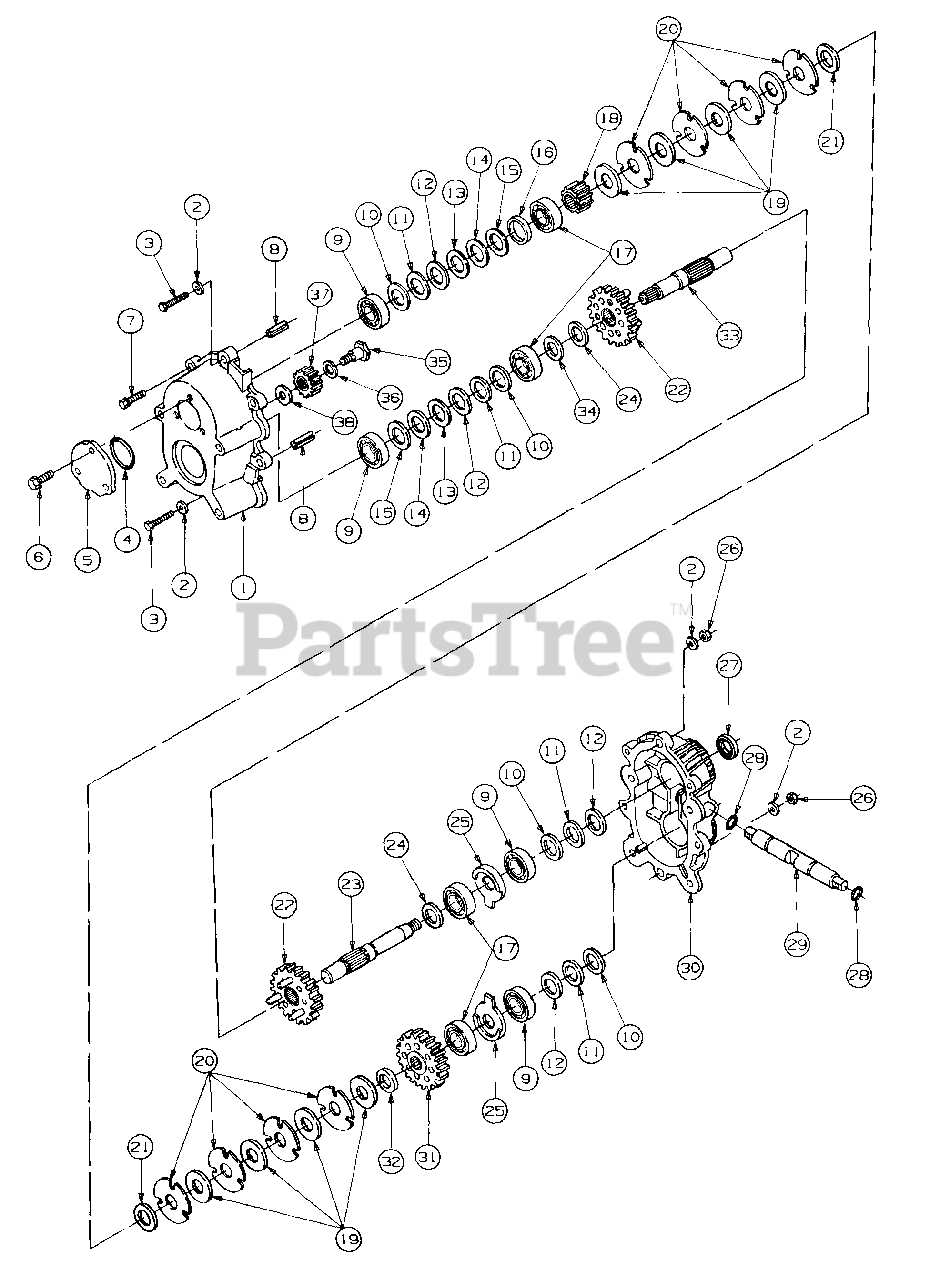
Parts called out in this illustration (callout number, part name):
1	Housing, Rear Clutch
2	Washer, Flat, .25 x .62 x .052 Thk
3	Screw, Hex Cap, 1/4-20 x 1.5 Lg
4	O-Ring, 1.88 x .103
5	Plate, Clutch Shim
6	Screw, Hex TT-Tap, 1/4-20 x .62 Lg
7	Screw, Hex Wash TT-Tap, 1/4-20 x 1.0 Lg
8	Pin, Slotted Spring, 7/16 x 1.0 Lg
9	Bearing
10	Washer, Flat, 1.25 x 1.8 x .005 Thk
11	Washer, Flat, 1.25 x 1.8 x .010 Thk
12	Washer, Flat, 1.25 x 1.8 x .015 Thk
13	Washer, Flat, 1.25 x 1.8 x .020 Thk
14	Washer, Flat, 1.25 x 1.8 x .025 Thk
15	Washer, Flat, 1.25 x 1.8 x .062 Thk
16	Spacer, Clutch Input
17	Bearing, Angular Contact
18	Gear, 18T Spur
19	Plate, Clutch
20	Disc, Friction
21	Washer, Flat, 1.25 x 1.8 x .062 Thk
22	Carrier Assy, Clutch
23	Shaft, Input
24	Washer, Flat, .793 x 1.24 x .060 Thk
25	Fulcrum, Clutch
26	Nut, Hex Top Lock, 1/4-20
27	Seal, Input
28	O-Ring, 1/2 x 5/8
29	Shaft, Clutch Actuator
30	Housing, Front Clutch
31	Gear, 36T
32	Spacer, .915 ID x 1.25 OD x .148 Lg
33	Shaft, Output
34	Washer, Flat, .812 x 1.12 x .108 Thk
35	Shaft, Reverse Idler Gear
36	Washer, Flat, .50 x .86 x .030 Thk
37	Gear Assy, 16T Reverse Idler
38	Washer, Flat, .385 x 1.0 x .030 Thk
